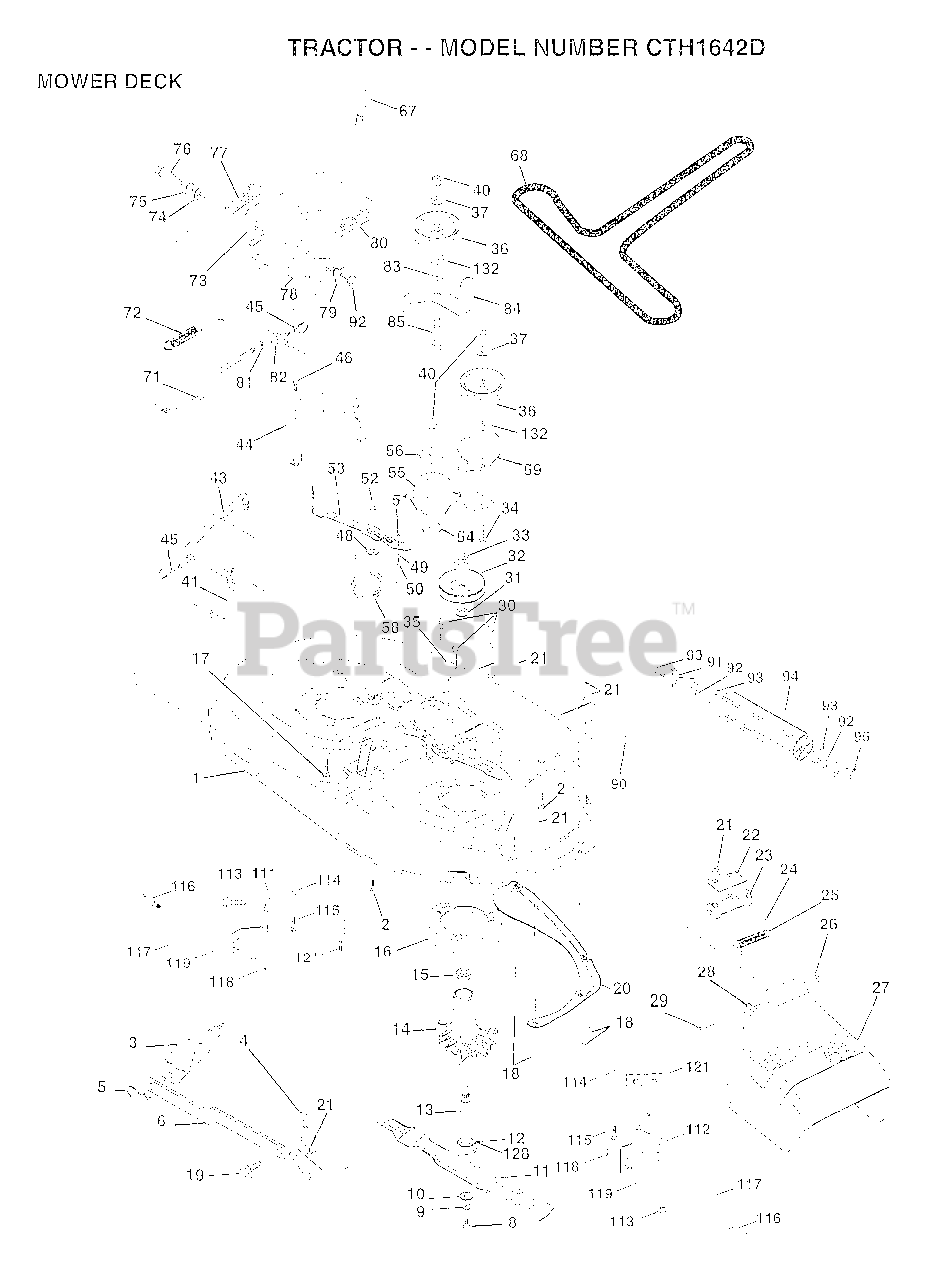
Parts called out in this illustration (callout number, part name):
1	DECK.WELD.42.
2	BOLT
3	BRKT ASM SWAY BAR
4	BRKT DECK SW BAR
8	BLADE BOLT
10	WASHER.HARD.BLADE
11	"BLADE.42"" HIPERF"
12	BEARING.BALL
14	HSG ASM MANDREL
15	BEARING
16	STRIPPER RND MWR
17	BOLT RDHD 3/8-16
18	BOLT
19	BOLT SHD 5/16-18
22	STIFFENER BRKT
23	DEFLECTOR BRKT
24	CAP-SLEEVE LT
25	SPRING TORSION
26	NUT PUSH M
27	DEFLECTOR.SHIELD
28	WASHER
29	HINGE ROD
31	WASHER
32	PULLEY.MANDREL.42
34	BOLT
35	XMAS TREE FASTNER
36	FLAT IDLER PULLEY
37	WASHER
41	PIVOT ROD
43	ROD CLUTCH W/NIBS
44	GUARD MAND LH BLK
45	RETAINER M
46	SCREW.1/4-20X5/8
48	HARD SMALL WASHER
49	ROLLER ASM-CAM
50	SHOULDER BOLT
51	LOCKNUT
52	BOLT.SHLD.5/16-18
54	HARDENED WASHER
55	ARM-IDLER
56	SPACER RETAINER
58	SPRING TORSN BRAK
59	GUARD IDLER TUV
68	BELT.V.T-PATH
71	ROD CLUTCH 38/42
72	RETURN SPRING
73	CLUTCH ARM SECOND
74	WASHER
75	RING
76	SHOULDER BOLT
77	SPRING KEEPER
78	LOWER ASM CLUTCH PRIMARY YP
79	BUSHING
80	SPRING.CLUTCH.MWR
81	NUT
82	TRUNION ADJ
83	WASHER
84	"KEEPER-BELT,FIXED"
85	BOLT RDHD 3/8-16
90	BOLT
92	NUT
93	WASHER
111	BRACKET.GWHL.LH.
112	BRACKET.GWHL.RH.
113	SCREW
116	BOLT.SHOULDER
117	WHEEL.GUAGE.MED.
118	LOCKNUT
119	WASHER
121	BRACKET.EXTRD.GWL
128	WASHER.FELT.
132	WASHER GT
